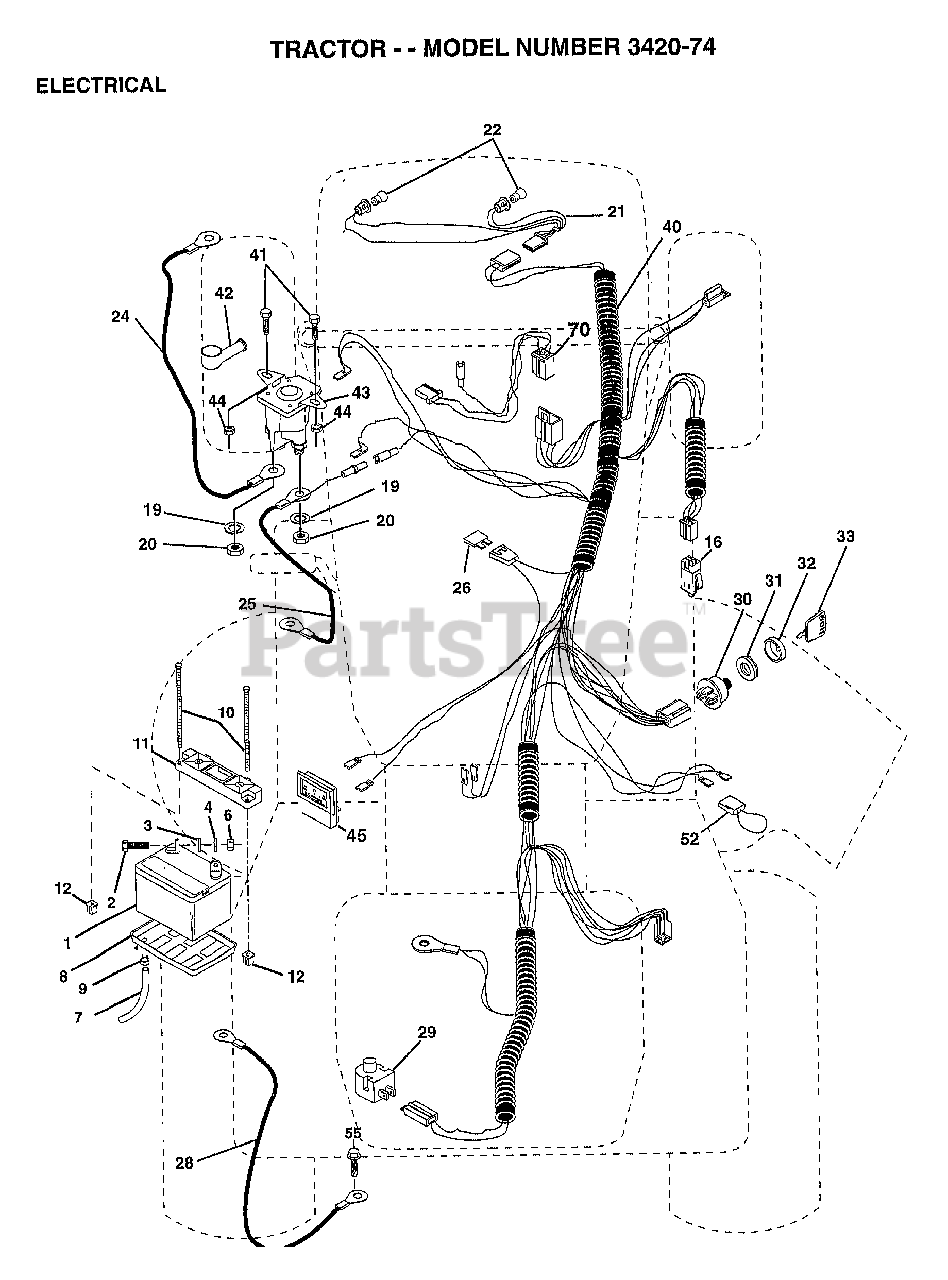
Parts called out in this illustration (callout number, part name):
2	BOLT LT
3	WASHER
4	LOCKWASHER
7	"DRAIN TU T, BATT"
8	"TRAY T, BATTERY"
9	HOSE CLAMP T
11	HOLDDOWN BATTERY
16	SWITCH INTERLOCK
20	NUT
21	"HARNESS,LIGHT SOC"
22	HEADLAMP BULB
24	"CABLE T, BATTERY"
25	CABLE.6GA.22W/16W
26	FUSE HYT
28	CABLE.GRND.6GA.21
29	SWITCH SEAT
30	SWITCH IGN 4POS
31	NUT IGNITION
32	COVER KEY SWITCH
33	KEY
40	"HARNESS-IGN,YDPRO"
41	BOLT HXHD FIN
44	NUT HXKEP 1/4X20
52	PROTECTION LOOP
55	SCREW LT
70	HARNESS ENG DUAL
